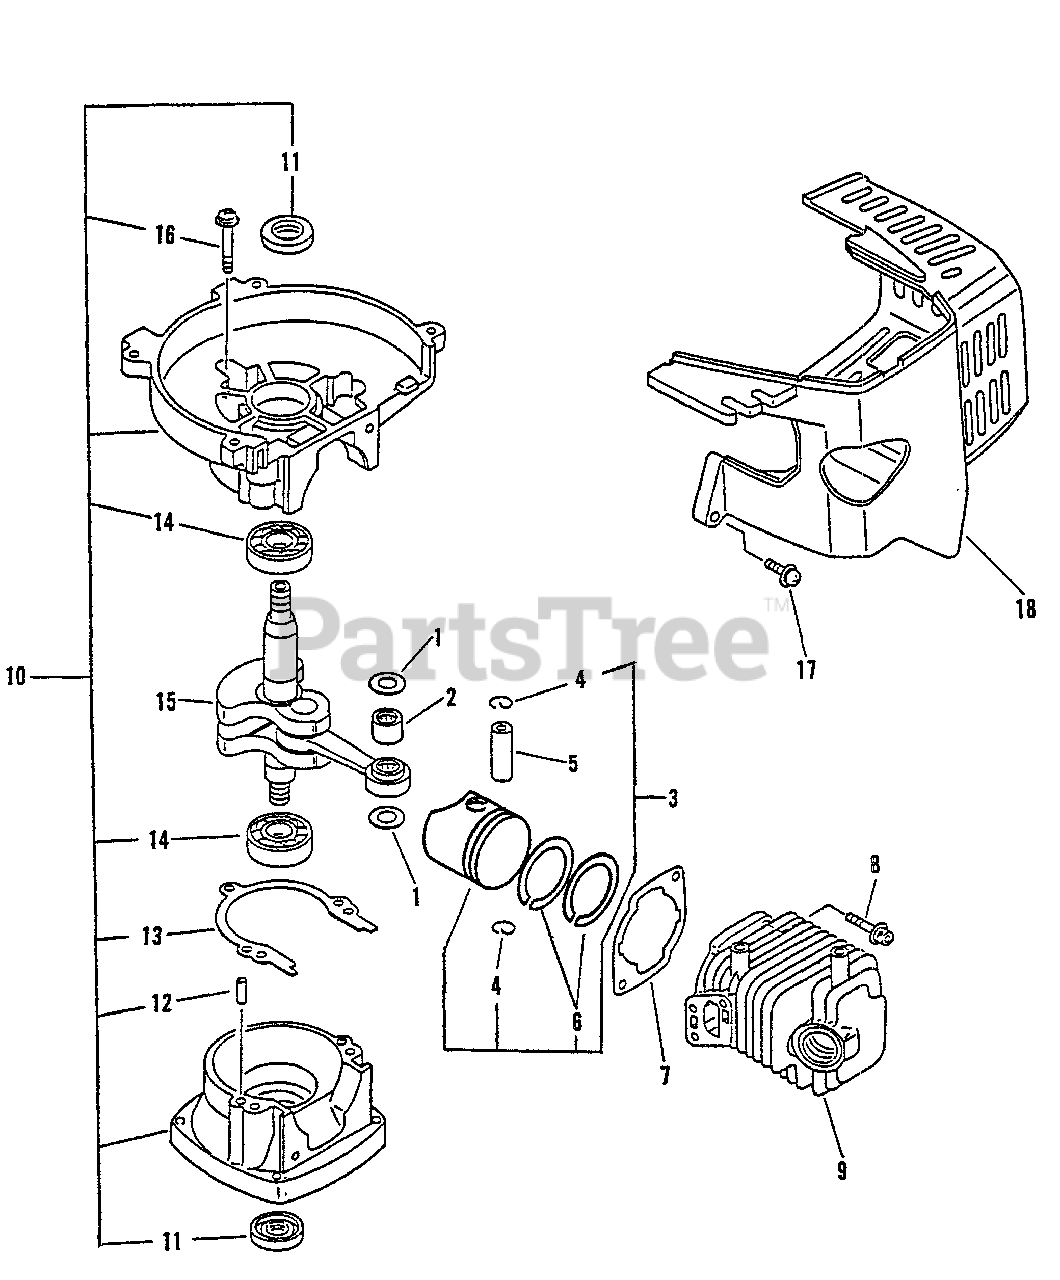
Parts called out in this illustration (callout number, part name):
1	WASHER, THRUST
2	BEARING, NEEDLE
3	PISTON KIT
4	RING, SNAP
5	PIN, PISTON 8
6	RING, PISTON
7	GASKET, CYLINDER
8	BOLT 5×22
9	CYLINDER
10	CRANKCASE KIT
11	SEAL, OIL 12
12	PIN, LOCATING 4
13	GASKET, CRANKCASE
14	BEARING, BALL - 6201 C3
15	CRANKSHAFT ASSY
16	BOLT 5×28
17	SCREW 4×22
18	COVER, ENGINE
